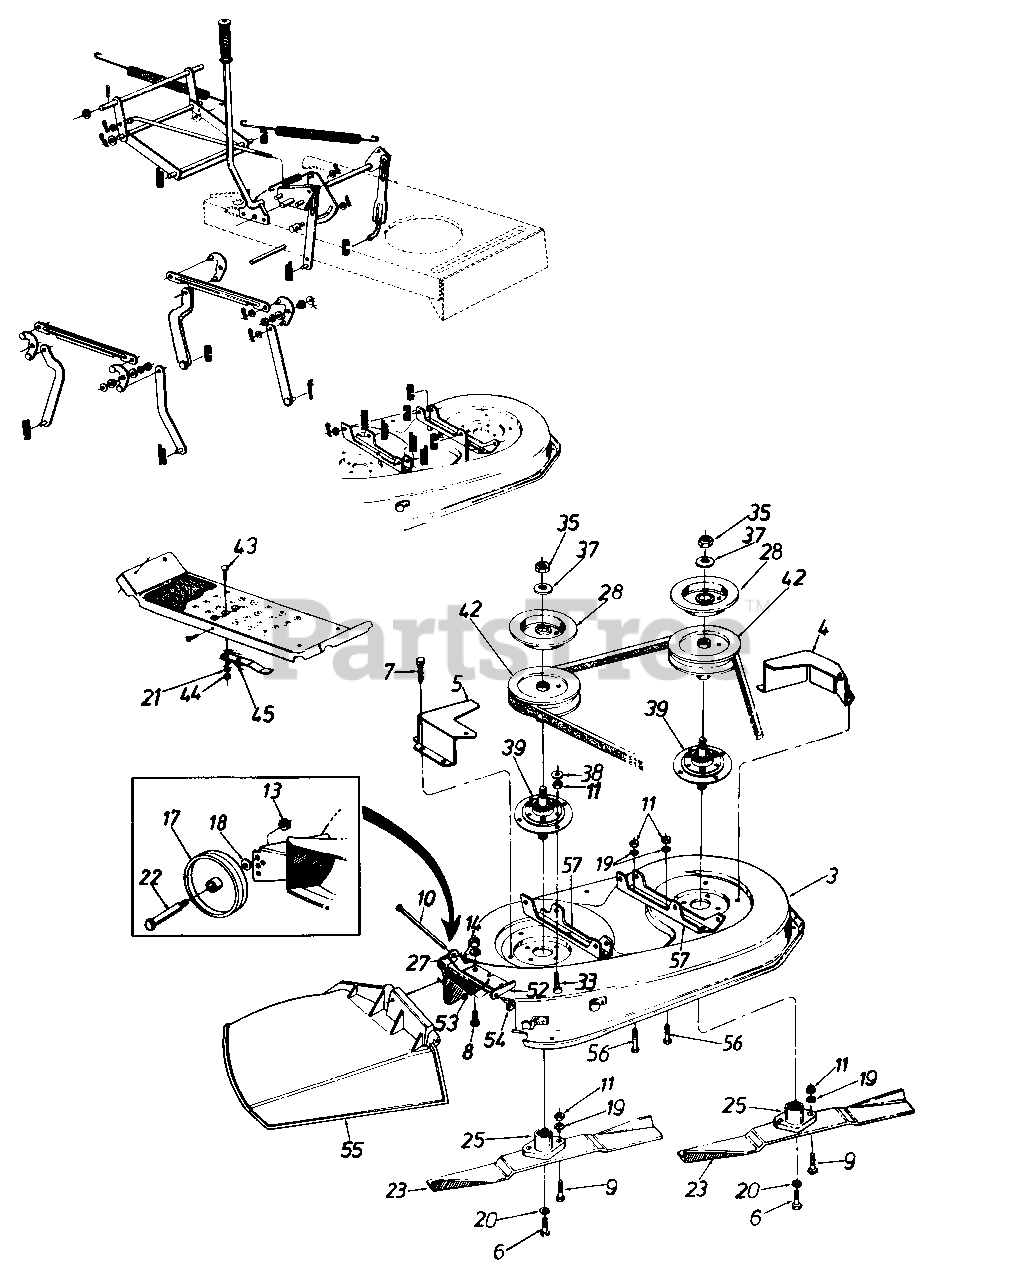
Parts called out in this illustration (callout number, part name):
3	42" Deck Ass'y.
6	Hex Bolt 3/8-24 x 1.0" Lg.
7	Hex Wash. Hd. TT-Tap Scr. l/4-20 x .5" Lg.
8	Truss Mach. Scr. 1/420 x .75"
9	Hex Bolt Special 5/16-24 x 1.0"
10	HingePin
11	Hex Nut 5/16-24 Thd.
13	Hex Top L-Nut 3/8-16 Thd.
14	Hex Nut 1/-20 Thd.
17	Deck Wheel-5"
18	Bell-Wash. .40" l.D. x .88" O.D.
19	L-Wash. 5/16" l.D.
20	L-Wash. 3/8" l.D.-H.D.
21	L-Wash. 1/4" l.D.
22	Shld. Bolt 498" Dia. x 1.53n
23	High-Lift Blade
25	Blade Adapter
27	Bell-Wash. 1/4 l.D.
28	Brake Disc
33	Hex Bolt 5/16-24 x 75" Lg.
35	Hex Jam Nut 5/8-18 Thd.
37	L-Wash. 5/8 I.D.
38	L-Wash. 5/16" I.D.
39	Blade Spindle Ass'y. Comp.
42	5.5 Dia. Pulley
43	Carr. Bolt 1/4-20 x .62
44	Hex Nut 1/4-20 Thd.
45	Blade Brake Ass'y.
52	Hinge Mtg. Brkt.
53	Torsion Spring
55	Chute Ass'y. Comp.
56	Hex Bolt 5/16-24 x .75 Lg.
